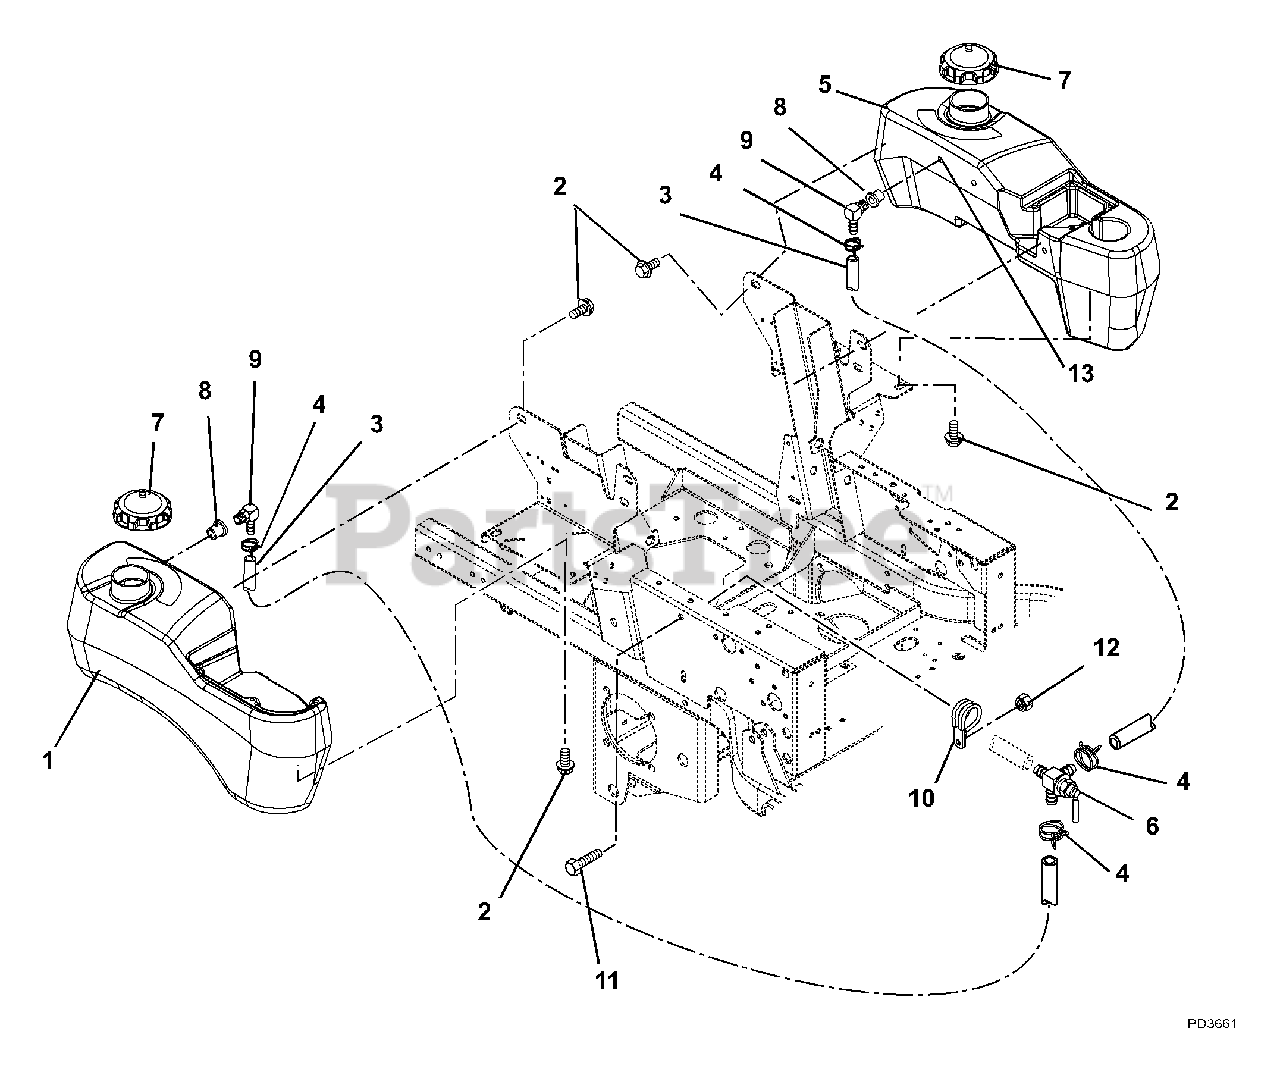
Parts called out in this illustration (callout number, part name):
1	Tank, Gas - Right Hand
2	Bolt, Hex .31-18 x .75 Grade 5
3	Gas Line, Bulk .25" ID
4	Hose, Clamp
5	Tank, Left Hand Fuel
6	Valve, Fuel
7	Cap, Gas
8	Grommet, Orange
9	Fuel Tank Fitting
10	Clamp, Cushioned Steel
11	Bolt, Hex .38-16 x 1.00 Grade 5
12	Nut, Locking Top Flange .38-16
13	20" Fuel Line Kit (inside of tank)
